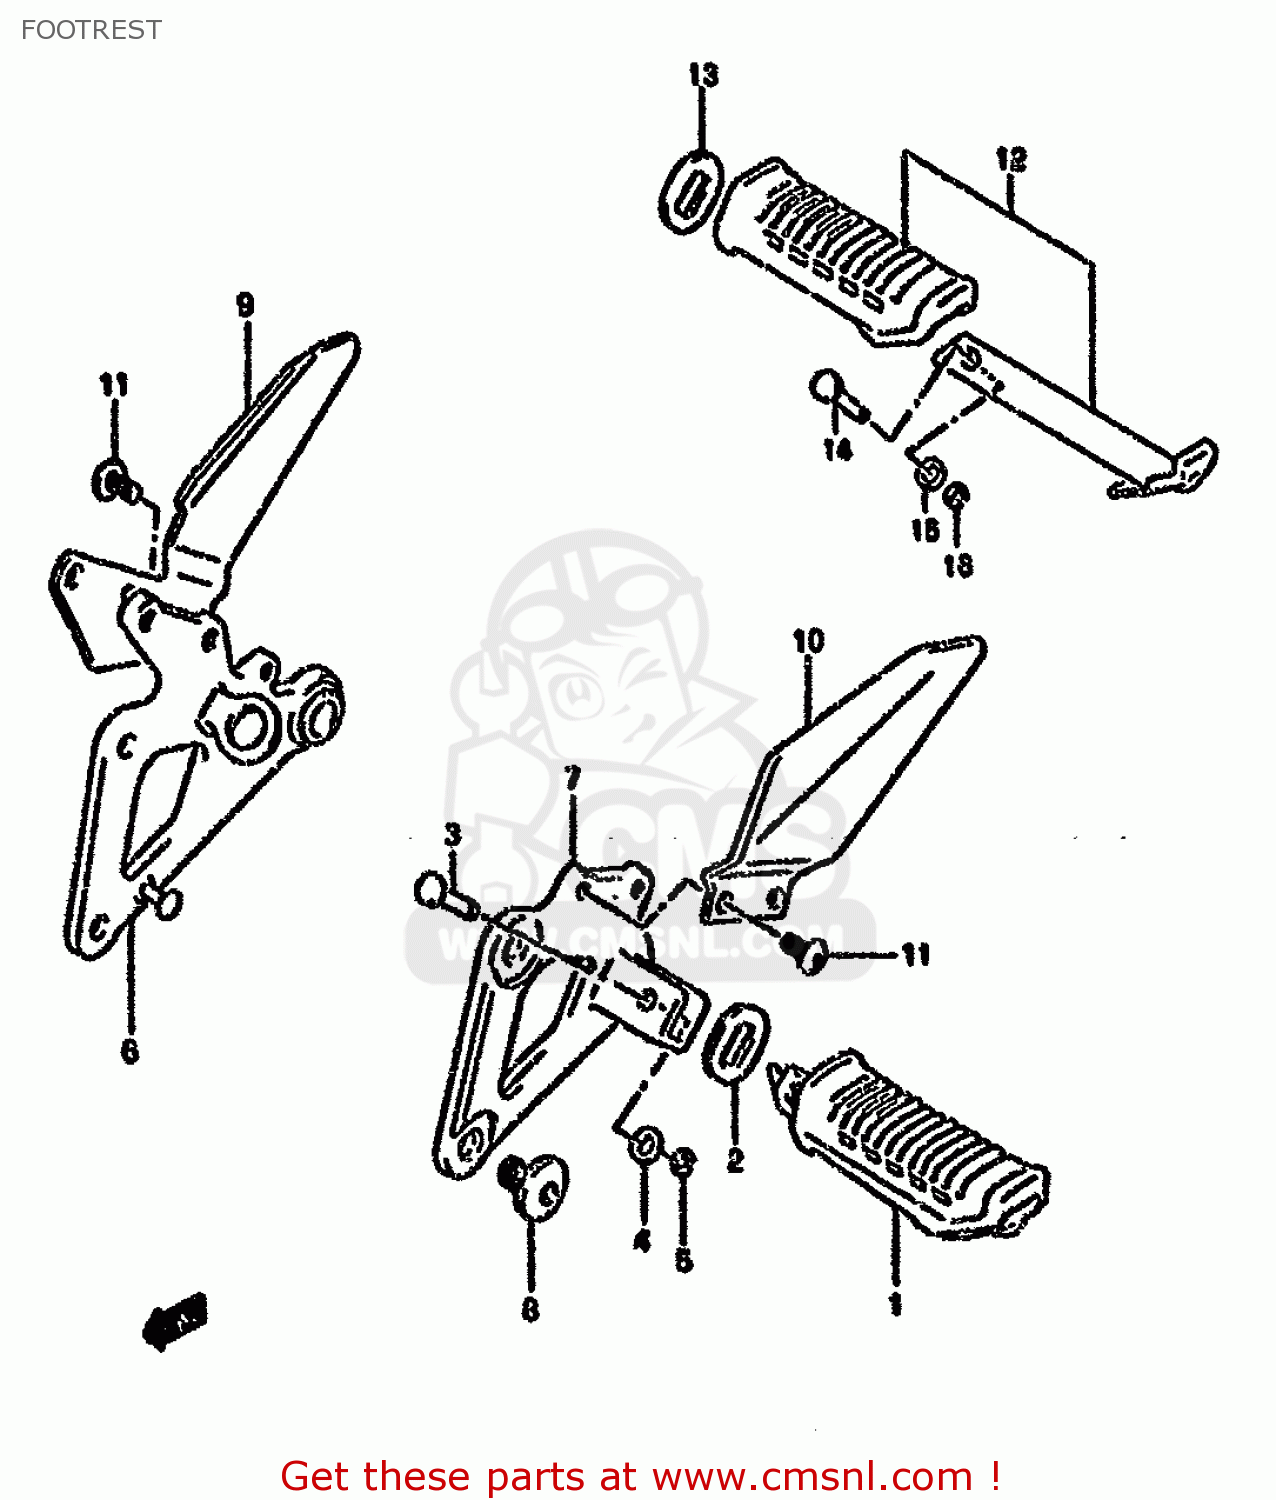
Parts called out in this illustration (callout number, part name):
1	RUBBER,FR FOOTREST,R
2	WASHER,FOOTREST RUBBER
3	PIN
4	WASHER
5	E RING
6	BRACKET COMP,FRONT FOOTREST
7	BRACKET,FR FOOTREST,L
8	BOLT(8X25)
9	GUARD,FRONT FOOTREST,RIGHT
10	GUARD,FRONT FOOTREST,LEFT
11	SCREW
12	FOOTREST ASSY,PILLION,R
13	WASHER,FOOTREST RUBBER
14	PIN
15	WASHER
16	E RING
